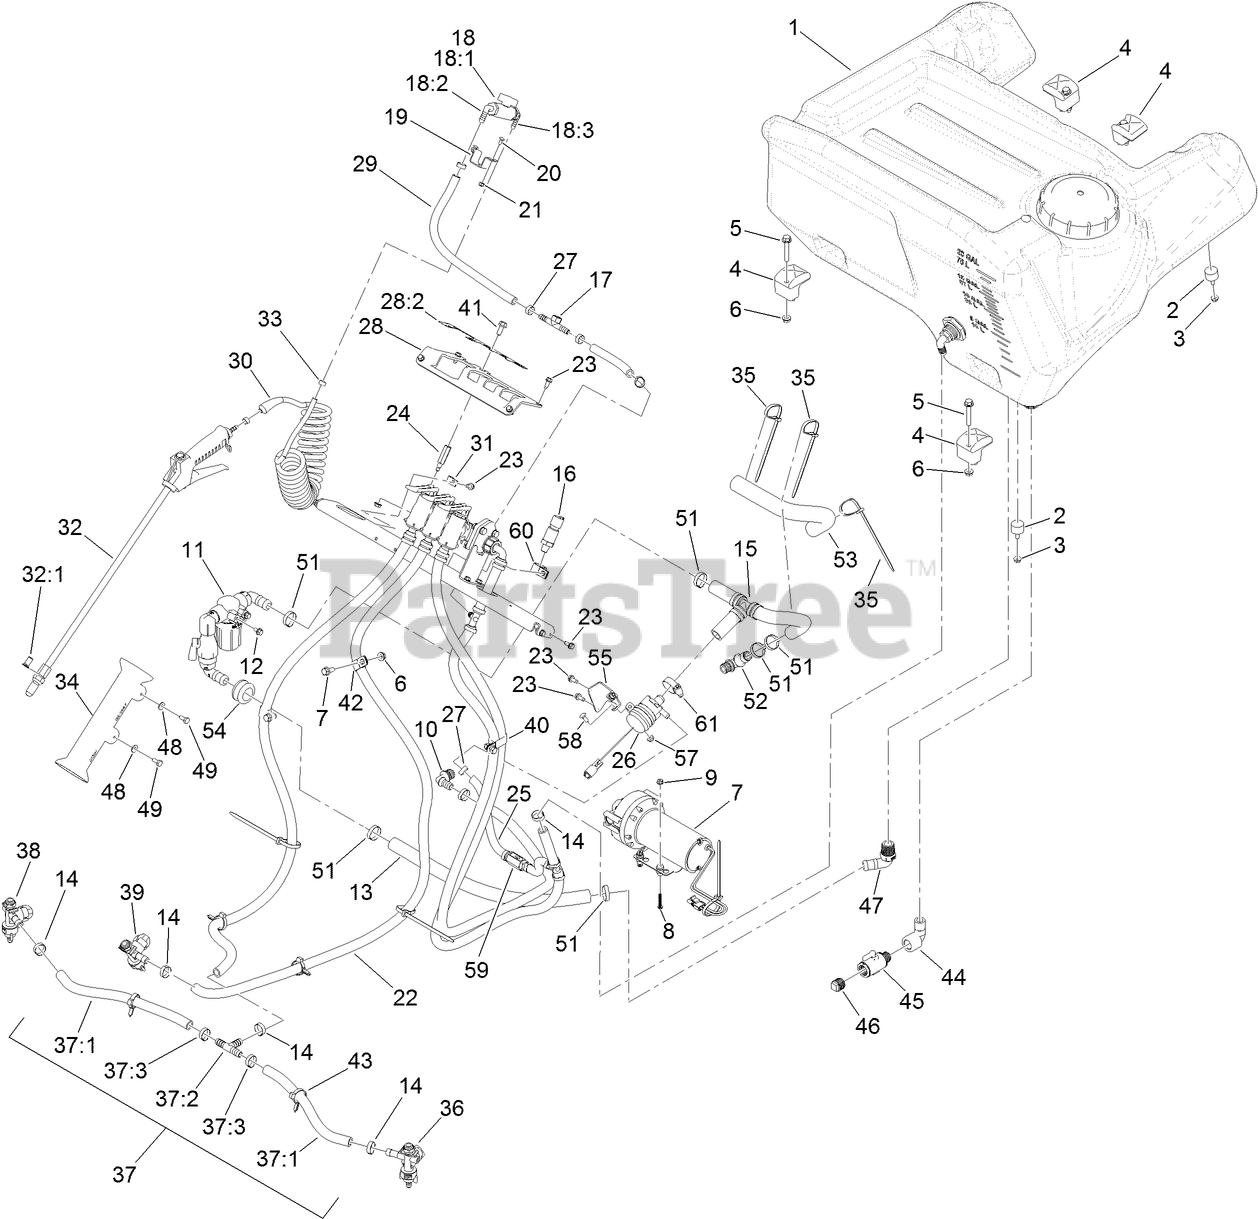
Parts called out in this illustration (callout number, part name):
1	TANK-SPRAYER
2	BUMPER
3	NUT-HF
5	SCREW-HHF
6	NUT-HF
7	PUMP-DIAPHRAGM, 3.8 GPM
8	SCREW-SHWH
9	NUT-HF
10	FITTING-ELBOW, BARBED
11	STRAINER ASM
12	SCREW-HHF
13	HOSE-WATER
14	CLAMP OETIKER 0.716" CLOSED 0.826" OPEN
15	ASM-, 3/4 PVC REINFORCED WATER HOSE
16	TRANSDUCER-PRESSURE
17	FITTING-TEE
18	WAND CONTROL ASM
18:1	VALVE-BALL
18:2	FITTING-ELBOW-90
18:3	FITTING-ELBOW-90
19	BRACKET-VALVE
20	BOLT-CARR
21	NUT-LOCK, NI
22	MANIFOLD-VALVE, CONTROL ASM
23	SCREW-HWH
24	SPACER, MANIFOLD MOUNT
25	HOSE-WATER
26	PUMP-CENTRIFUGAL
28	COVER-CONTROLS
28:2	DECAL-LEVER CONTROL
29	HOSE-WATER, 3/8 PVC RED
30	HOSE-COILED
31	CLAMP-R
32	SPRAY WAND ASM
32:1	STRAINER-NOZZLE, 50M 5PSI CHECK
34	HOLDER-WAND
35	TIE-CABLE
36	LEFT NOZZLE SUB ASM
37	HOSE ASM
37:1	HOSE-WATER
37:2	FITTING-TEE
37:3	CLAMP OETIKER 0.716" CLOSED 0.826" OPEN
38	RIGHT NOZZLE SUB ASM
39	CENTER NOZZLE SUB ASM
41	SCREW-HHF
42	CLIP-LOOM
43	CLAMP-HOSE
44	ELBOW-90 DEG
45	MICROVALVE
47	ELBOW-HOSEBARB
48	WASHER-FLAT
49	SCREW-HH
52	FITTING-ELBOW
53	SLEEVE-CORRUGATED, SPLIT
54	GROMMET
55	BRKT-RECIR PUMP
57	NUT-HF
58	SCREW-CARR
59	VALVE-3/8 CHECK
60	R-CLAMP
61	CLAMP-HOSE
